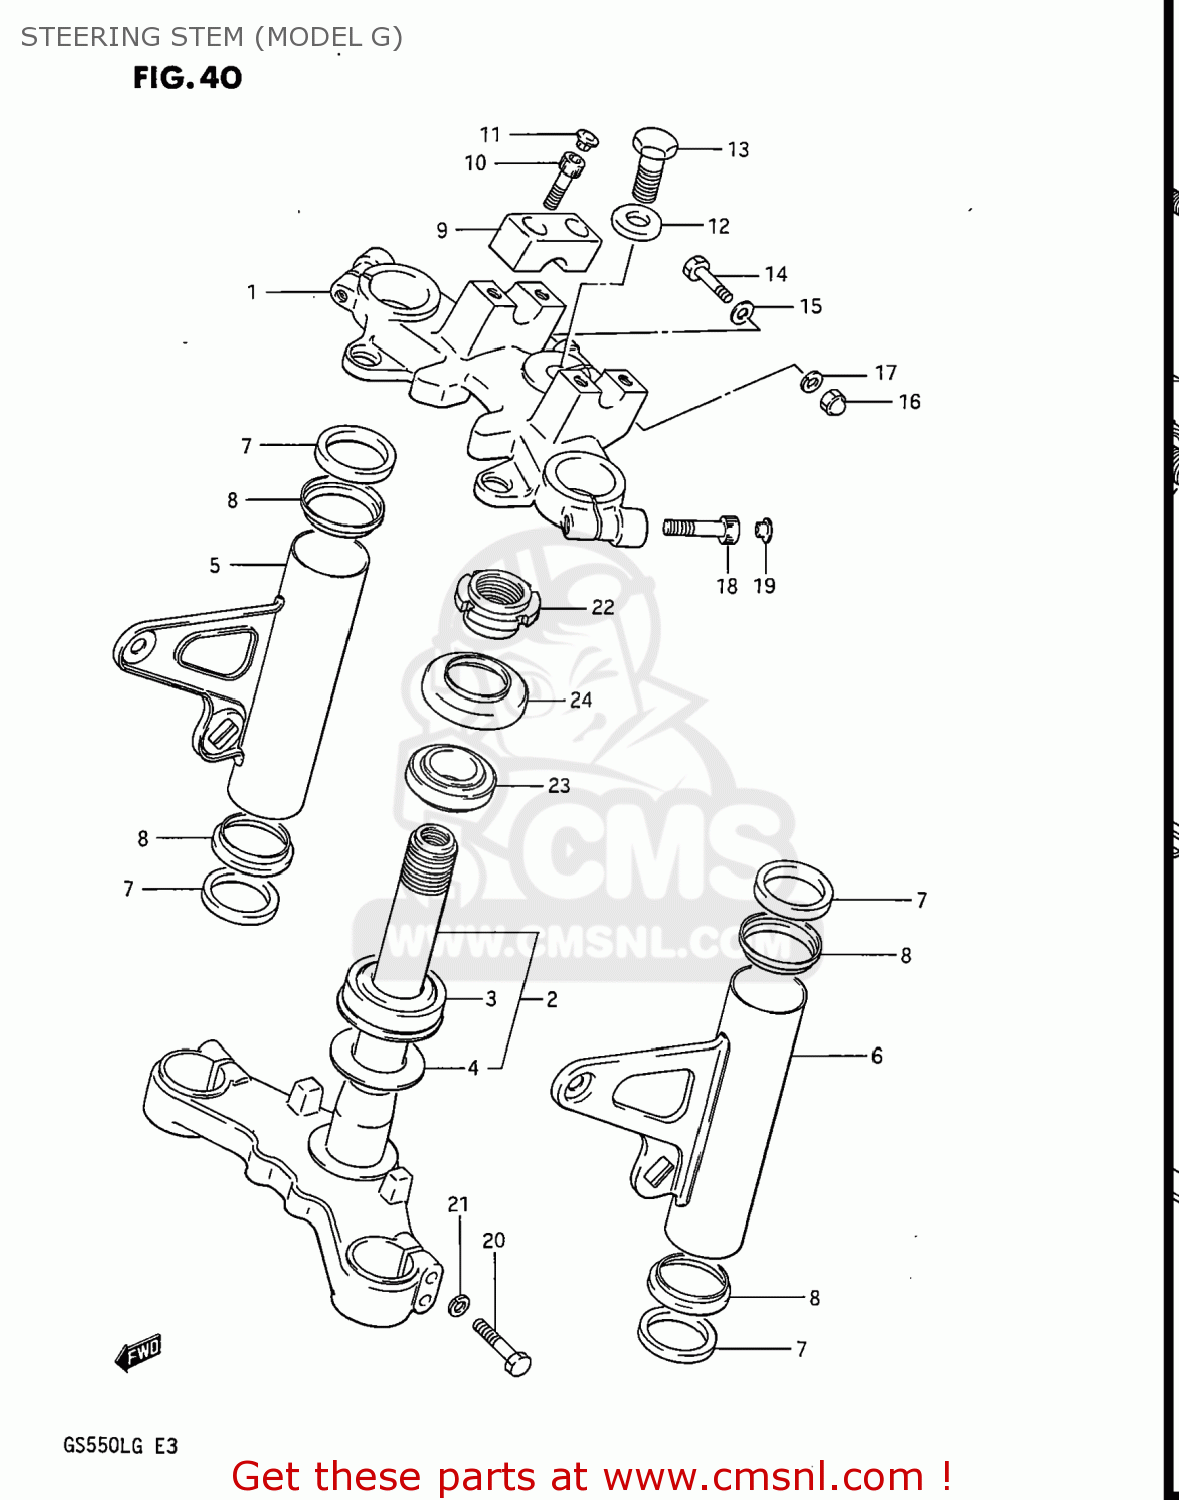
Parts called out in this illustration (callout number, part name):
1	HEAD,STEERING STEM
2	STEM,STEERING
3	BEARING
4	WASHER,THRUST
5	BRACKET COMP,HEADLAMP
6	BRACKET,HEADLAMP,LEFT
7	CUSHION,HEADLAMP BRACKET
9	HOLDER,HANDLEBAR
10	BOUT
11	CAP(OD:14.5)
12	WASHER,STEERING STEM
13	BOLT,STEERING STEM HEAD
14	BOLT 8X50
15	WASHER
16	NUT
17	LOCK WASHER
18	BOLT, CENTER
19	CAP(OD:20)
20	BOLT 8X40
21	WASHER,LOCK,8.
22	NUT,STEERING STEM
23	TAPER,ROLLER BEARING
24	DUST SEAL,STEERING UPR
